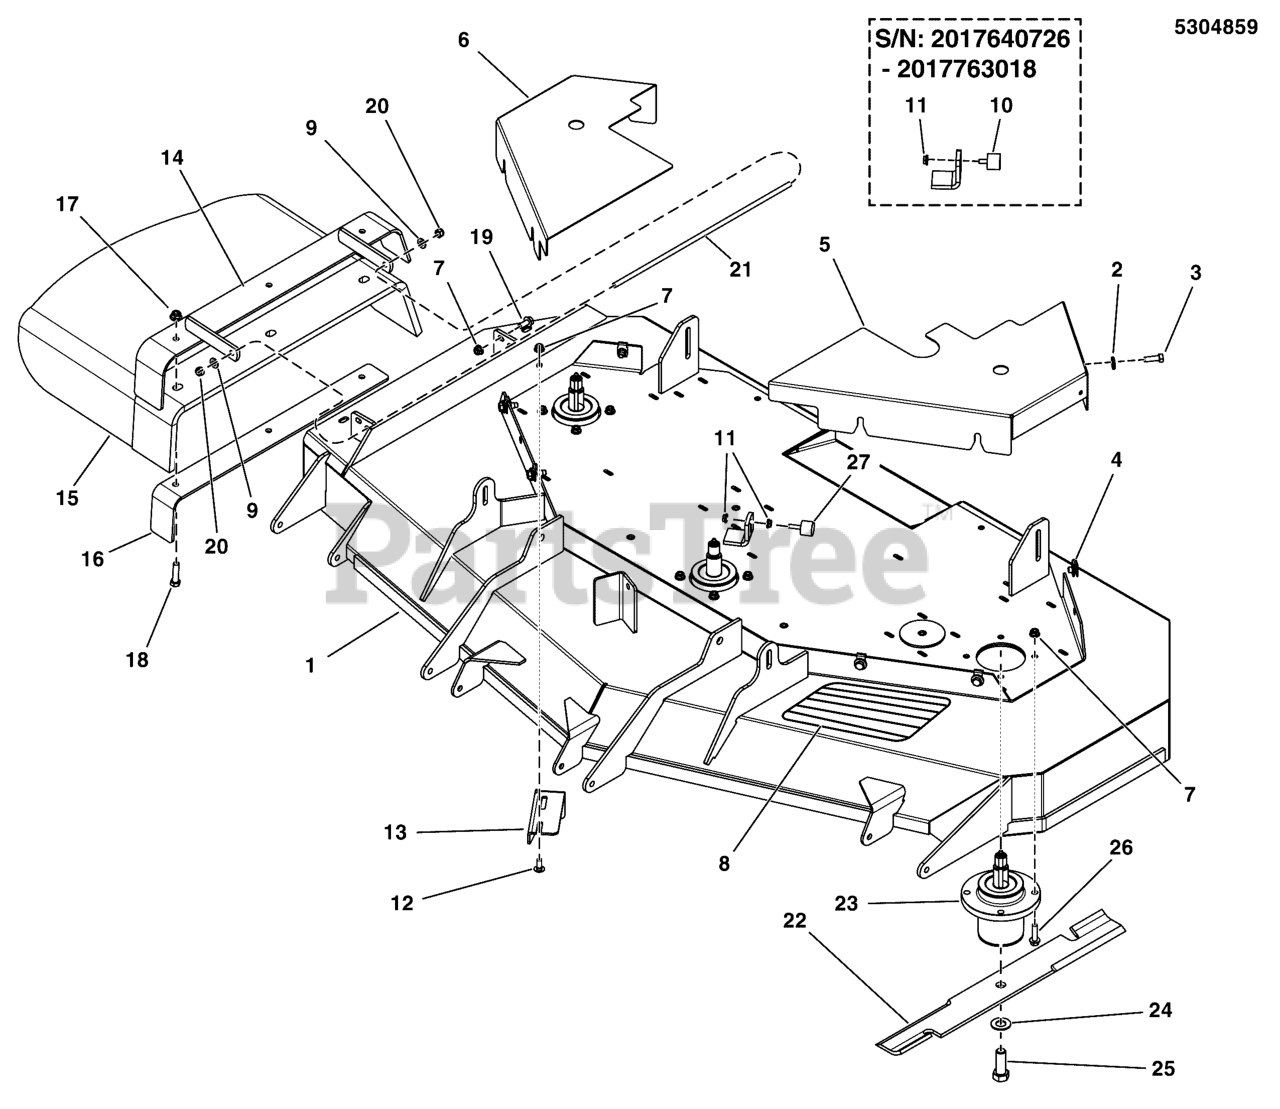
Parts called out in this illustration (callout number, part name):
1	DECK SHELL W/ DECALS, 61, 125 (5415801D)
2	WASHER, 5/16" SAE
3	BOLT, 5/16-18 X 1" GRD5 YZ
4	BODY CLIP, 5/16-18-7GA MATERIAL
5	PLATE, GUARD, 61, LH - RED
6	PLATE, GUARD, 61, RH - RED
7	NUT, 5/16-18 HEX NYLOCK FLANGE NUT
8	SAFETY WALK, 4.00 X 7.50
9	WASHER, 5/16" SAE
10	BUMPER, RUBBER, 1/4-20
11	NUT, 1/4-20 HEX SERR. FLANGE
12	BOLT, 5/16-18 X 3/4, CARRIAGE, GD5, CZ
13	PLATE, DEFLECTOR - BLK
15	CHUTE, RUBBER DISCHARGE (5104442)
16	SUPPORT, DISCHARGE CHUTE - BLK
17	NUT, 3/8 - 16 HEX NYLOCK FLANGE
18	BOLT, 3/8-16 X 1-1/2, CARRIAGE, GD5, CZ
19	BOLT, 5/16-18 X 3/4 GD5
20	NUT, 5/16-24 HEX NYLON LOCK
21	ROD, MOUNT, CHUTE, 61, CZ
22	BLADE SET, 61 DECK (3)
23	SPINDLE, ASSM, ALUMINUM - 5.25
24	WASHER, BLADE BOLT, 9/16" F436, CZ
25	BOLT, 5/8-11 X 1-3/4 GD8
26	BOLT, Flange Head, 5/16-18 x 1-1/4
27	BUMPER, RUBBER, 1/4-20 X 7/8" STUD
